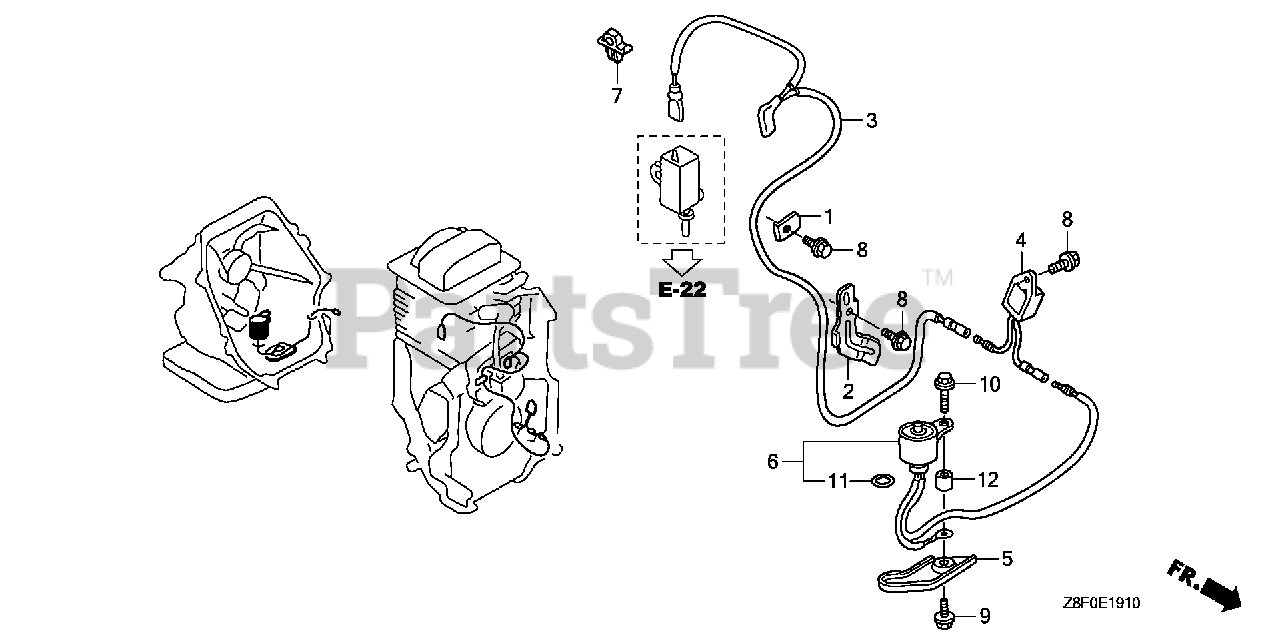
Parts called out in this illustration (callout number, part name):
1	CLAMP, STOP SWITCH WIRE
2	CLAMP, WIRE
3	WIRE, STOP SWITCH
4	ALERT UNIT, OIL
5	PROTECTOR, SWITCH
6	SWITCH, OIL LEVEL
7	HOLDER, STOP SWITCH WIRE Use up to Engine SN 2056819.
8	BOLT, FLANGE (6X13)
8	BOLT, FLANGE (6X12) (CT200)
9	BOLT, FLANGE (6X14)
10	BOLT, FLANGE (6X28) (CT200) Use up to Engine SN 1530314.
11	O-RING (11.8X2.4)
12	COLLAR (6.6X13.8X14.5)
